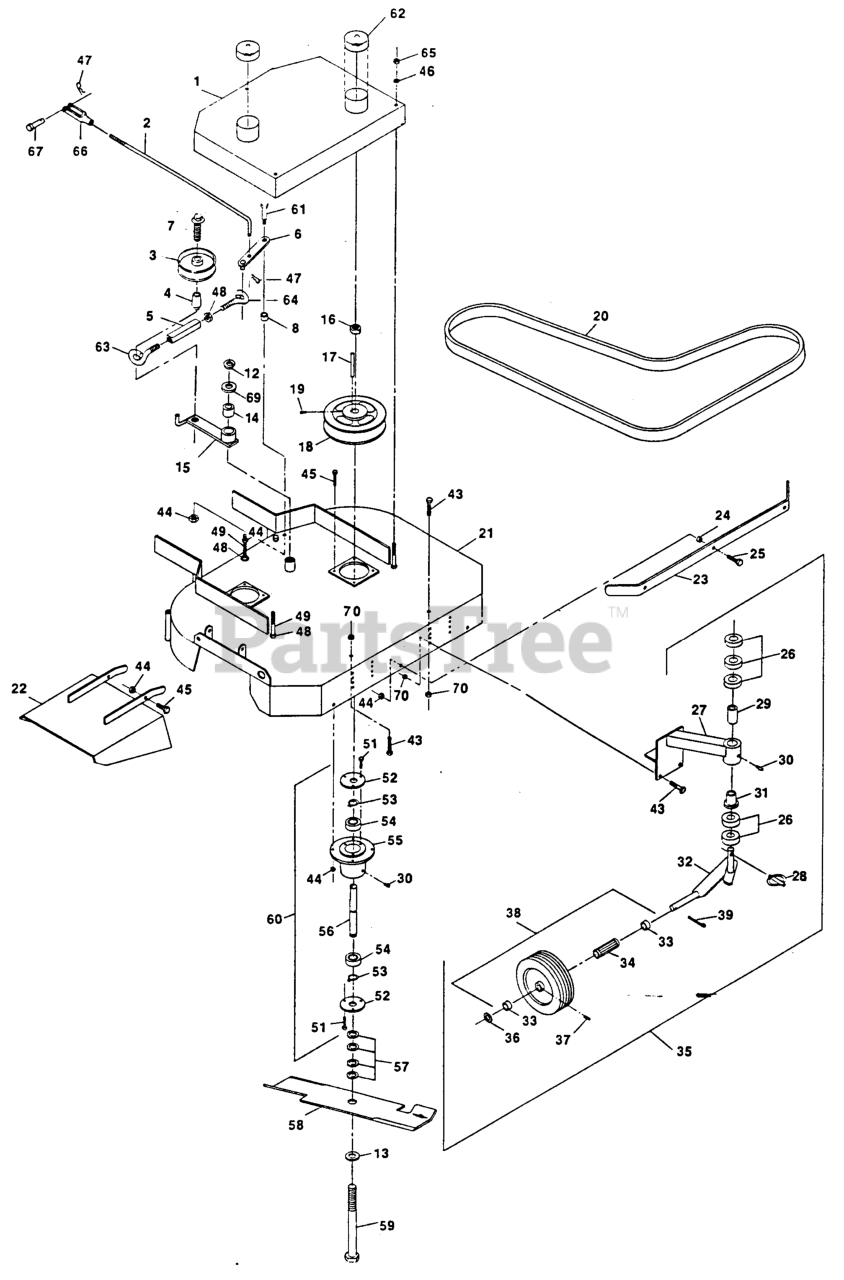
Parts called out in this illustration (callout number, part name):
5	BODY-TURNBUCKLE
14	BEARING,POWDERED METAL
18	PULLEY,CAST IRON
19	SCREW-SET
20	BELT,BLADE DRIVE
26	SPACER-CASTER
29	BEARING,STRAIGHT
32	WLD,STRUT CASTER
47	PIN-COTTER
49	BOLT,TAP HH
51	SCRWMACH PHS
55	HOUSING,CUTTER
56	SPINDLE,CUTTER
60	HOUSING,CUTTER COMPLETE
61	BOLT,SHLDR KSKH
62	CAP,SPINDLE GUARD
63	EYEBOLT-THREAD, LH
64	EYEBOLT-THREAD, RH
66	YOKE-ADJUSTABLE
67	PIN-CLEVIS
69	WASHER-SPINDLE
